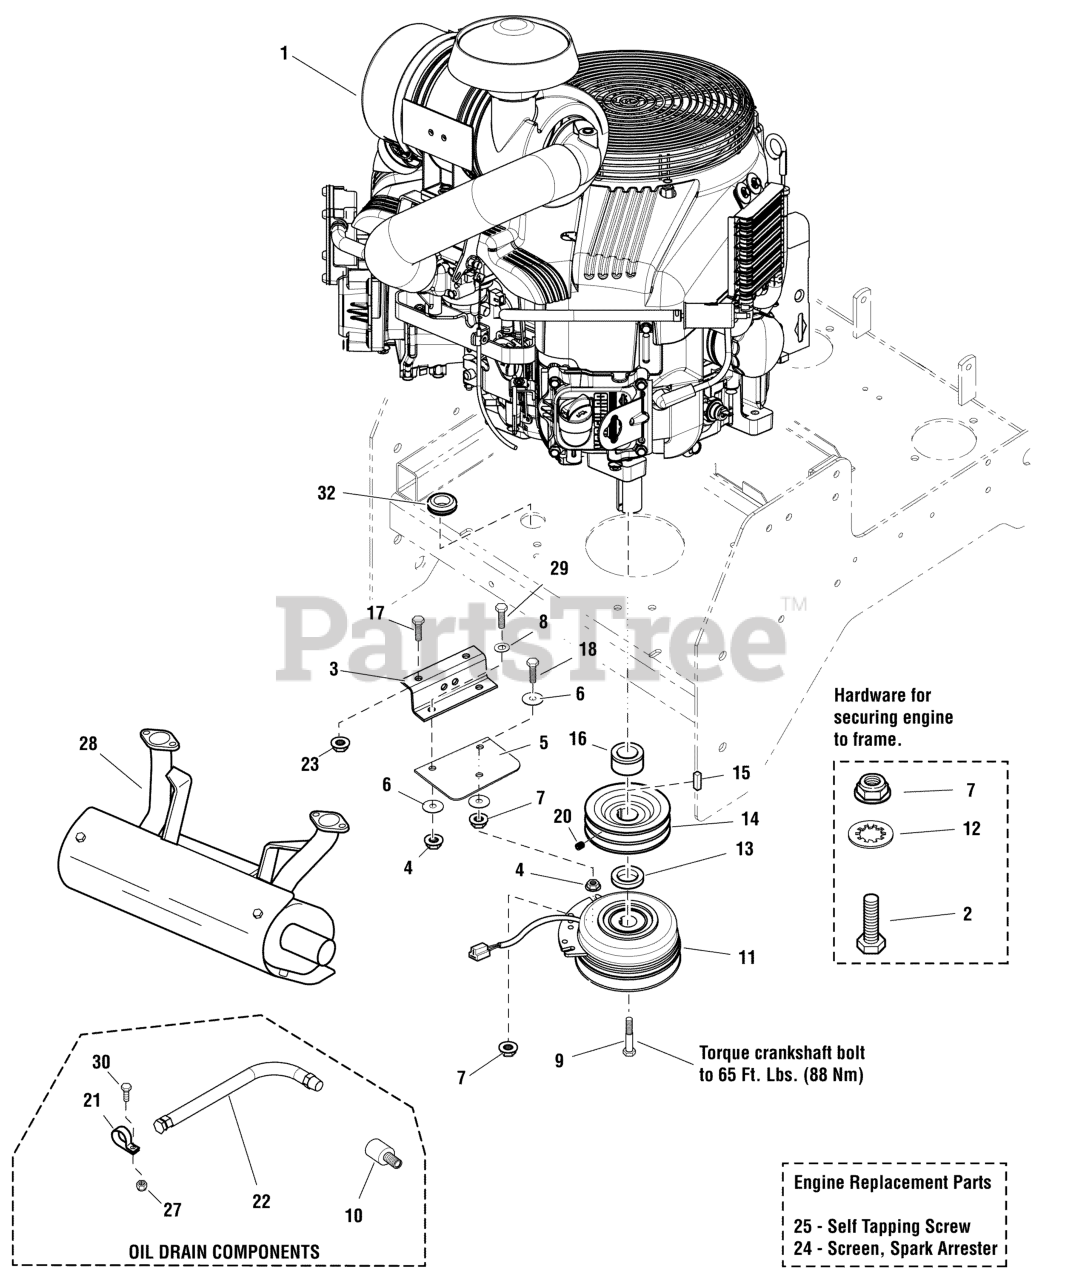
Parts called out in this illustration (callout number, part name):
1	* ENGINE, BRIGGS & STRATTON
2	BOLT, 5/16-18 X 1-3/4" GD5 YZ
3	ANCHOR, CLUTCH - BLK
4	NUT, 5/16-18 HEX SERRATED FLANGE (LARGE)
5	CLUTCH ANCHOR PAD
6	WASHER-3/8 FENDER
7	NUT, 5/16-18 HEX NYLOCK FLANGE
8	WASHER, 5/16" SAE
9	BOLT, CRANKSHAFT, 7/16" X 2-1/2
10	METRIC ADAPTER, M14-1.5" TO 3/8 NPTF
11	CLUTCH, WARNER,# 5218-158
12	WASHER, 5/16" INT. TOOTH LOCK
13	SPACER, 1.13 X 1.75 X .50
14	PULLEY, 5.25 OD X 1.126 ID
15	KEY, 1/4 SQ X 1
16	SPACER, 1.13 X 1.75 X 1.09, PM
17	NUT, 3/8-16 HEX NYLOCK FLANGE
18	BOLT, 5/16-18 X 2-1/4 TFL, GD5 YZ
20	SET SCREW, 5/16-18 X 3/8, KNURL, W/PATCH
21	CLAMP, VINYL
22	HOSE, OIL DRAIN
23	NUT, 3/8-16 HEX NYLOCK FLANGE
27	NUT, 1/4-20 HEX NYLOCK FLANGE
28	MUFFLER, ASSY, SERVICE PART
29	BOLT, 5/16-16 X 1" GD5 YZ
